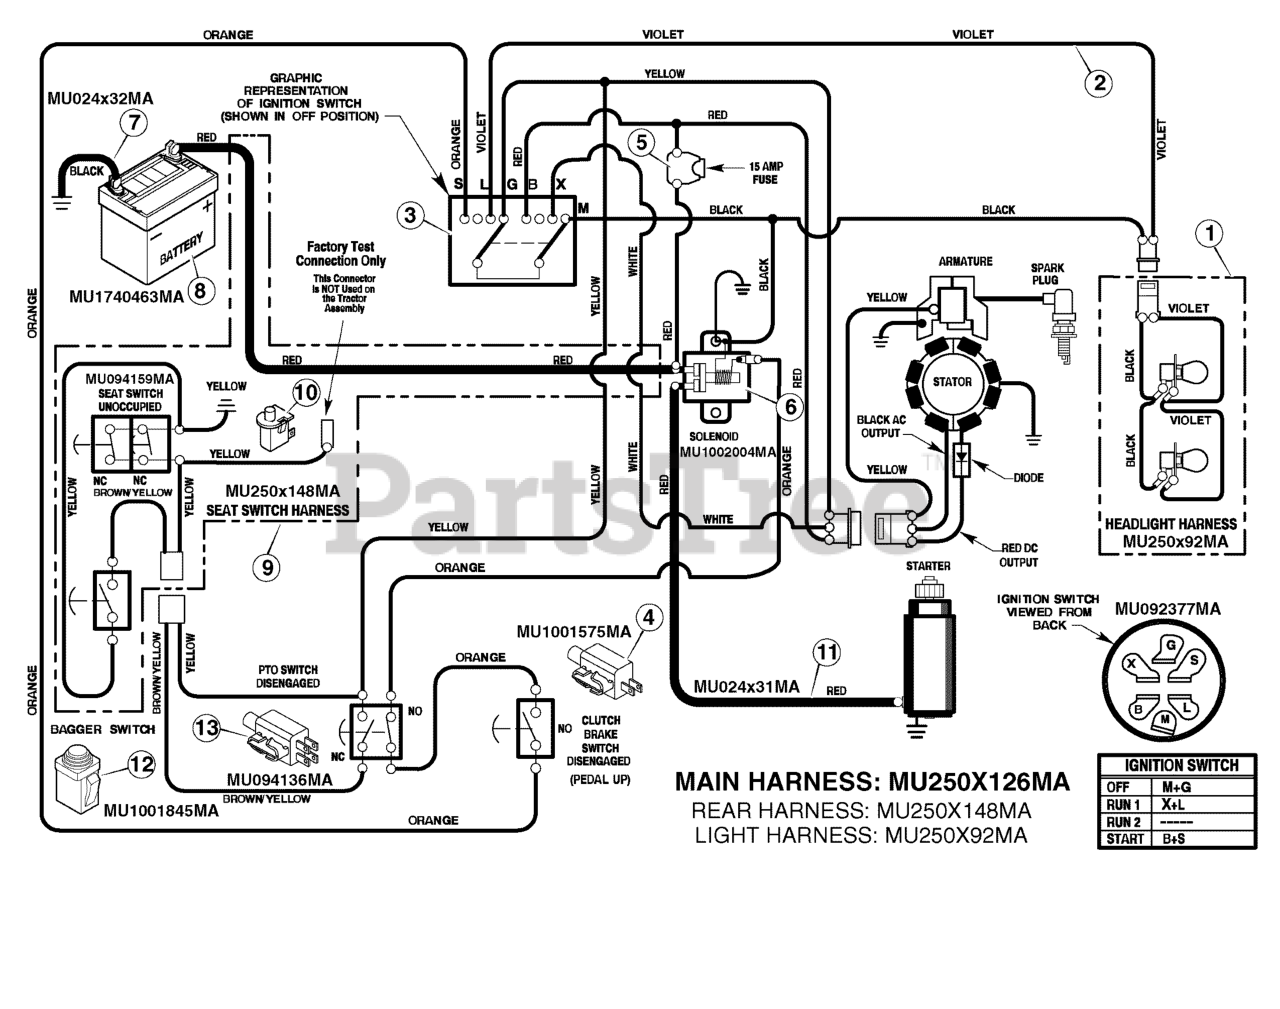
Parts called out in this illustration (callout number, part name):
1	Harness, Light Wire
2	Harness, Chassis Wire
3	Switch, Ignition
4	Switch, Limit
7	CABLE, Battery Ground
9	Harness, Seat Switch Wire
10	Switch, Seat Sensor
12	Switch, Bag Sensor
13	Switch, Limit
